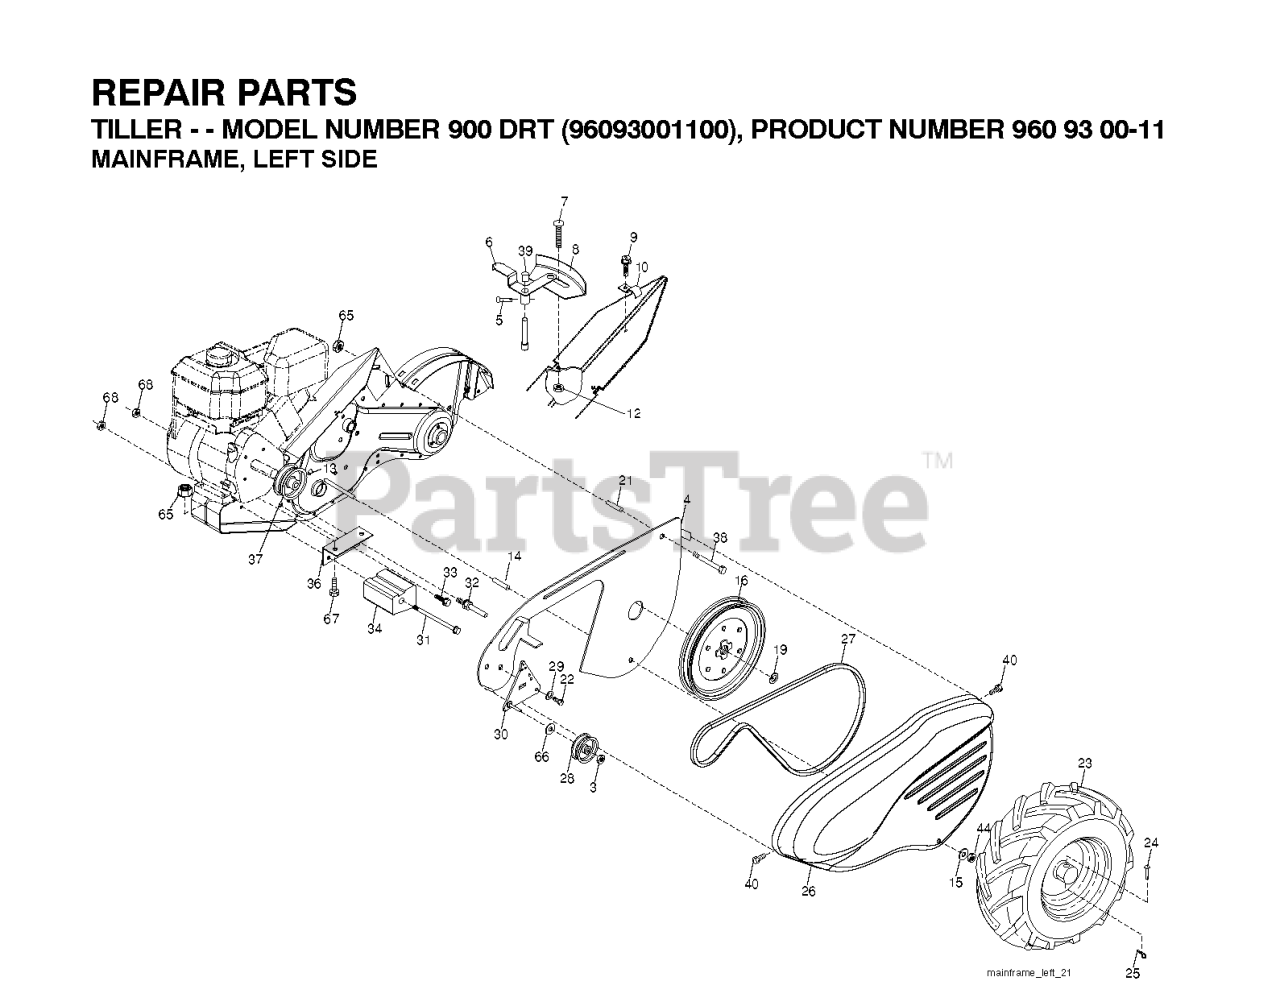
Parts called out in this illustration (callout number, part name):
3	NUT.HEX.3/8-16UNC
4	SHIELD
5	PIN.SPIROL.FLARED
6	LEVER.ASM.SHIFT.RED
8	RP.PANEL.SHIFT
9	TAPPING SCREW
10	CONDUIT.CLIP.PLATED
12	NUT
14	SPACER CRT
15	WASHER
16	SHEAVE, TRANSMISSION
19	RETAINING RING LT
21	SPACER-SPLIT.327 X .42
23	TIRE.13X5-6.CHEVRON.TILLER
24	RIVET,DRILLED
25	RETAINER M
26	RP BELT GUARD
27	V-BELT
28	PULLEY-IDLER TI
30	BRACKET.ASM.IDLER.BLACK
31	BOLT.FIN.HEX.3/8-16UNC
32	SHIFT ARM CRT
33	BOLT
34	COUNTERWEIGHT.LH.CRT
36	BRACKET LH CRT
37	RP.ENGINE PULLEY
38	BOLT
39	CAP.PLUNGER.BLACK
40	SCREW.HEX.WSH.SLT.#10-24X.50
44	NUT.71038.31-18.HEX.NYLOCK
65	LOCKNUT-FLANGE 5/16-18
66	WASHER
67	BOLT, HEX 5/16-18X1-3/4
